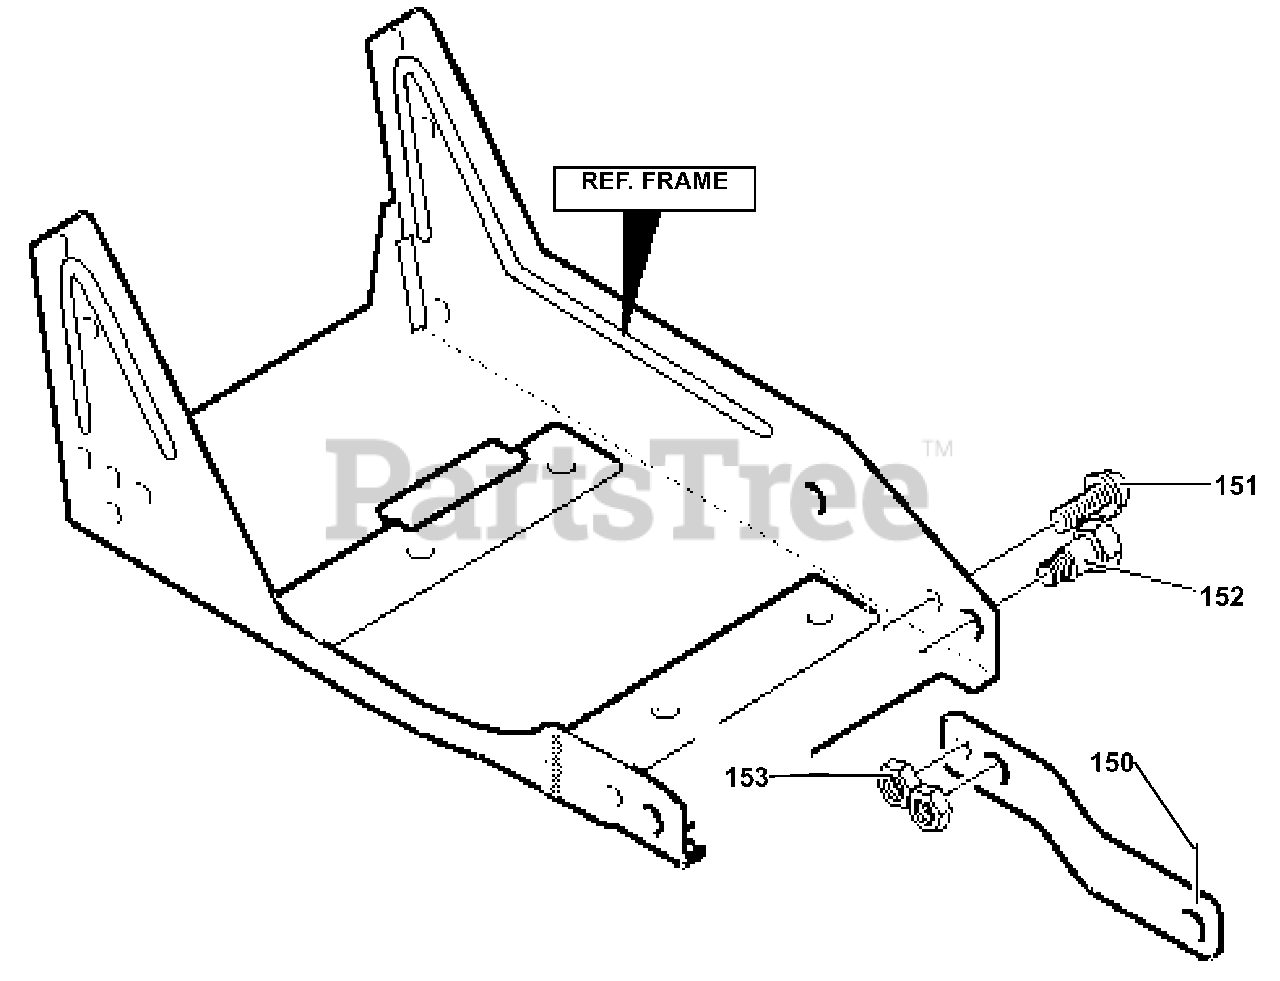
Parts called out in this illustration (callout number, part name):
150	Arm, Front Wheel
151	Screw, 5/16-18x.75
152	Sh. Bolt, 5/16-18
153	Nut, 5/16-18 Rghexctrlk
